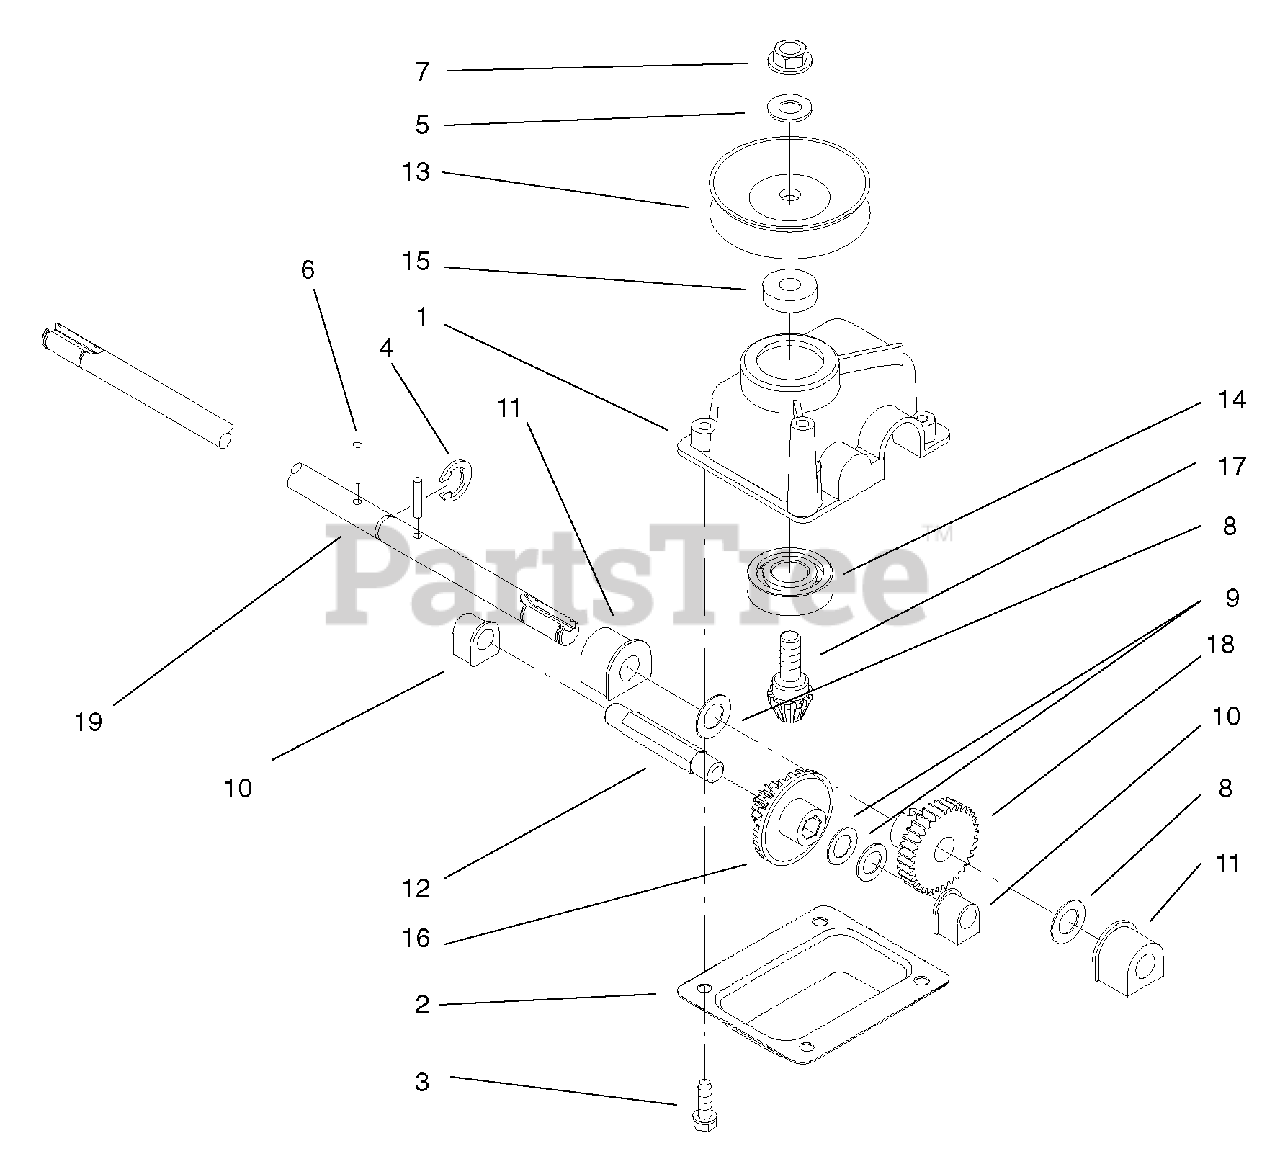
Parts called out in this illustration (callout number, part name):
1	Case-Gear
2	Cover-Case, Gear
3	Screw-HWH
4	Ring-Retaining
5	Washer-Flat
6	Pin-Groove
7	Nut-Lock, NI
9	Washer-Thrust
11	Bushing-Output
12	Shaft-Intermediate
13	Half-Pulley
14	Bearing-Ball
16	Gear-15t Spur, 37t Bevel
17	Gear-Pinion, Bevel
19	Shaft-Output
